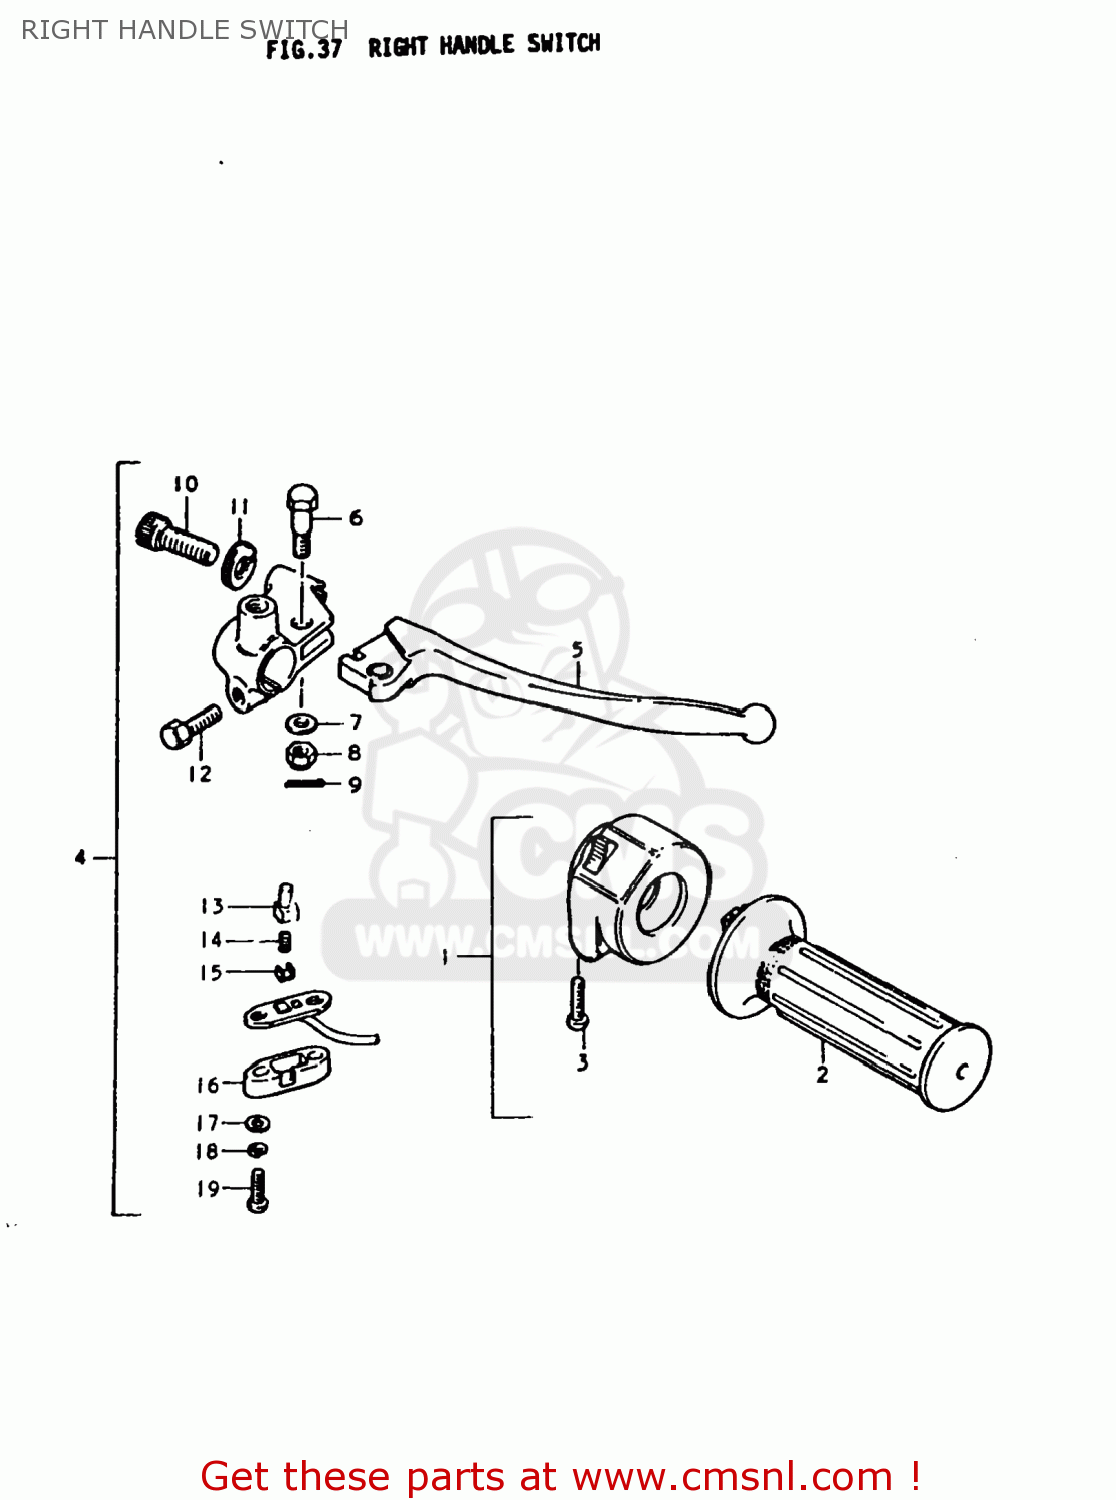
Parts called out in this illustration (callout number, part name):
1	GRIP ASSEMBLY,THROTTLE
2	GRIP,THROTTLE
3	SCREW
4	LEVER ASSEMBLY,BRAKE
5	LEVER,BRAKE
6	BOLT,LEVER
7	LOCK WASHER
8	NUT 6MM
9	COTTER PIN
10	ADJUSTER,CABLE
11	NUT,CABLE ADJUSTER
12	BOLT
13	HOLDER
14	SPRING
15	PLATE
16	COVER,FR BK TERMINAL BASE
17	WASHER
18	LOCK WASHER
19	SCREW
